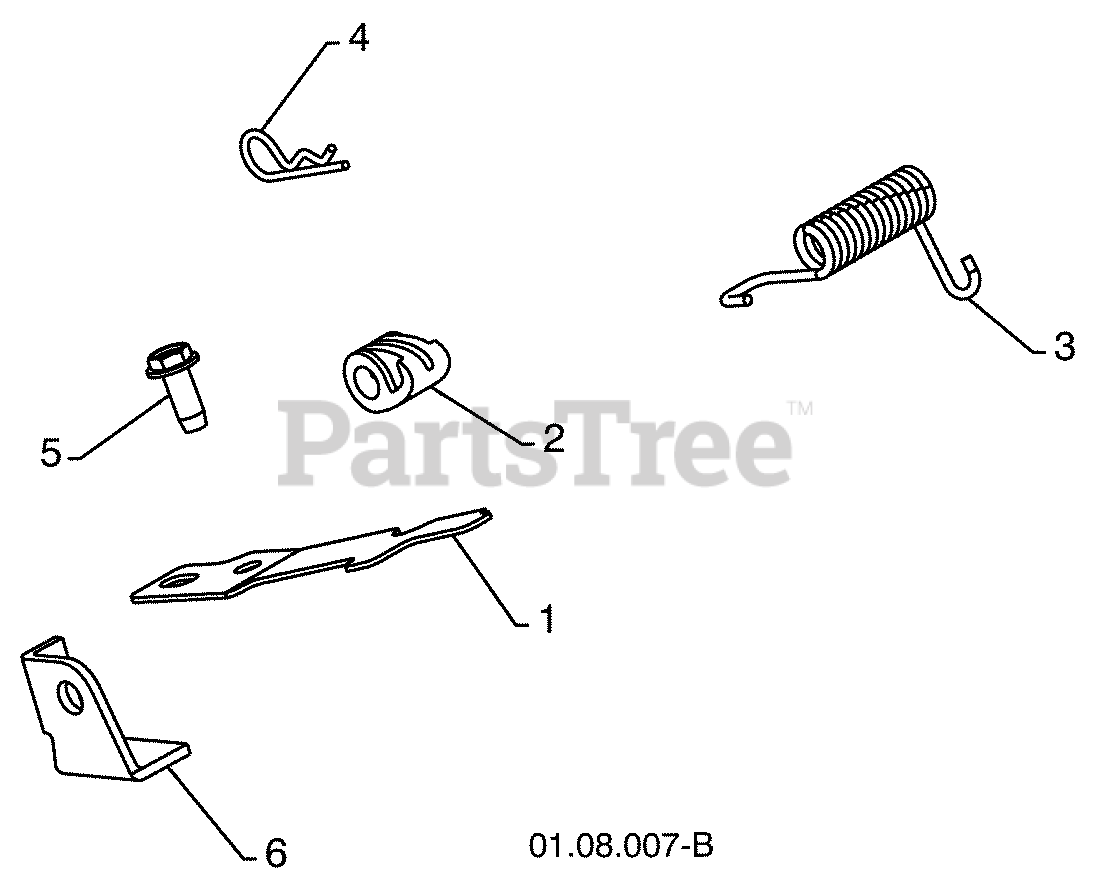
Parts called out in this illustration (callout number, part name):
1	INTERLOCK SPRING
2	INTERLOCK CAM
3	TORSION SPRING
5	SCREW 1/4-20 X .625
6	INTERLOCK STOP
